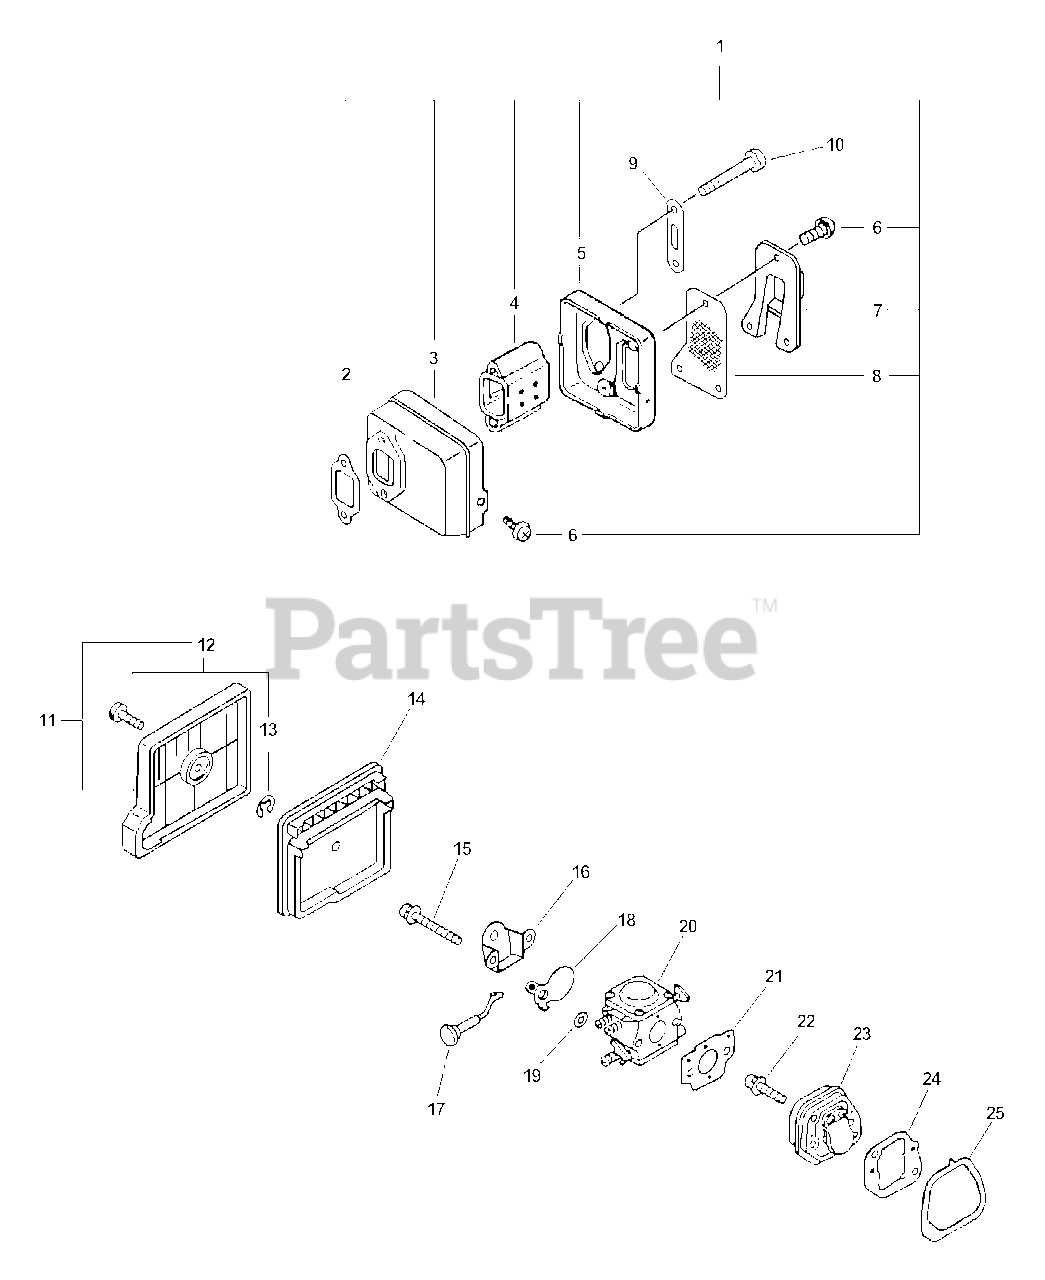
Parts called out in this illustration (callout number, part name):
1	MUFFLER ASSY
2	GASKET, MUFFLER
3	MUFFLER
4	SILENCER
5	COVER, MUFFLER
6	SCREW TAPPING 4×8
7	COVER, MUFFLER
8	SCREEN, SPARK ARRESTER
9	PLATE, EYE
10	BOLT 6 MM
11	COVER ASSY, AIR FILTER
12	THUMBSCREW
13	E-RING 4
14	FILTER, AIR
15	SCREW 5×45
16	PLATE, PREVENT
17	ROD, CHOKE
18	SHUTTER, CHOKE
19	WASHER 5.5×8×0.8
20	CARBURETOR - WT-385A
20	CARBURETOR - WT-402A
21	GASKET, INTAKE
22	SCREW 5×18
23	INSULATOR KIT
24	GASKET, INTAKE
25	SEAL, INTAKE
